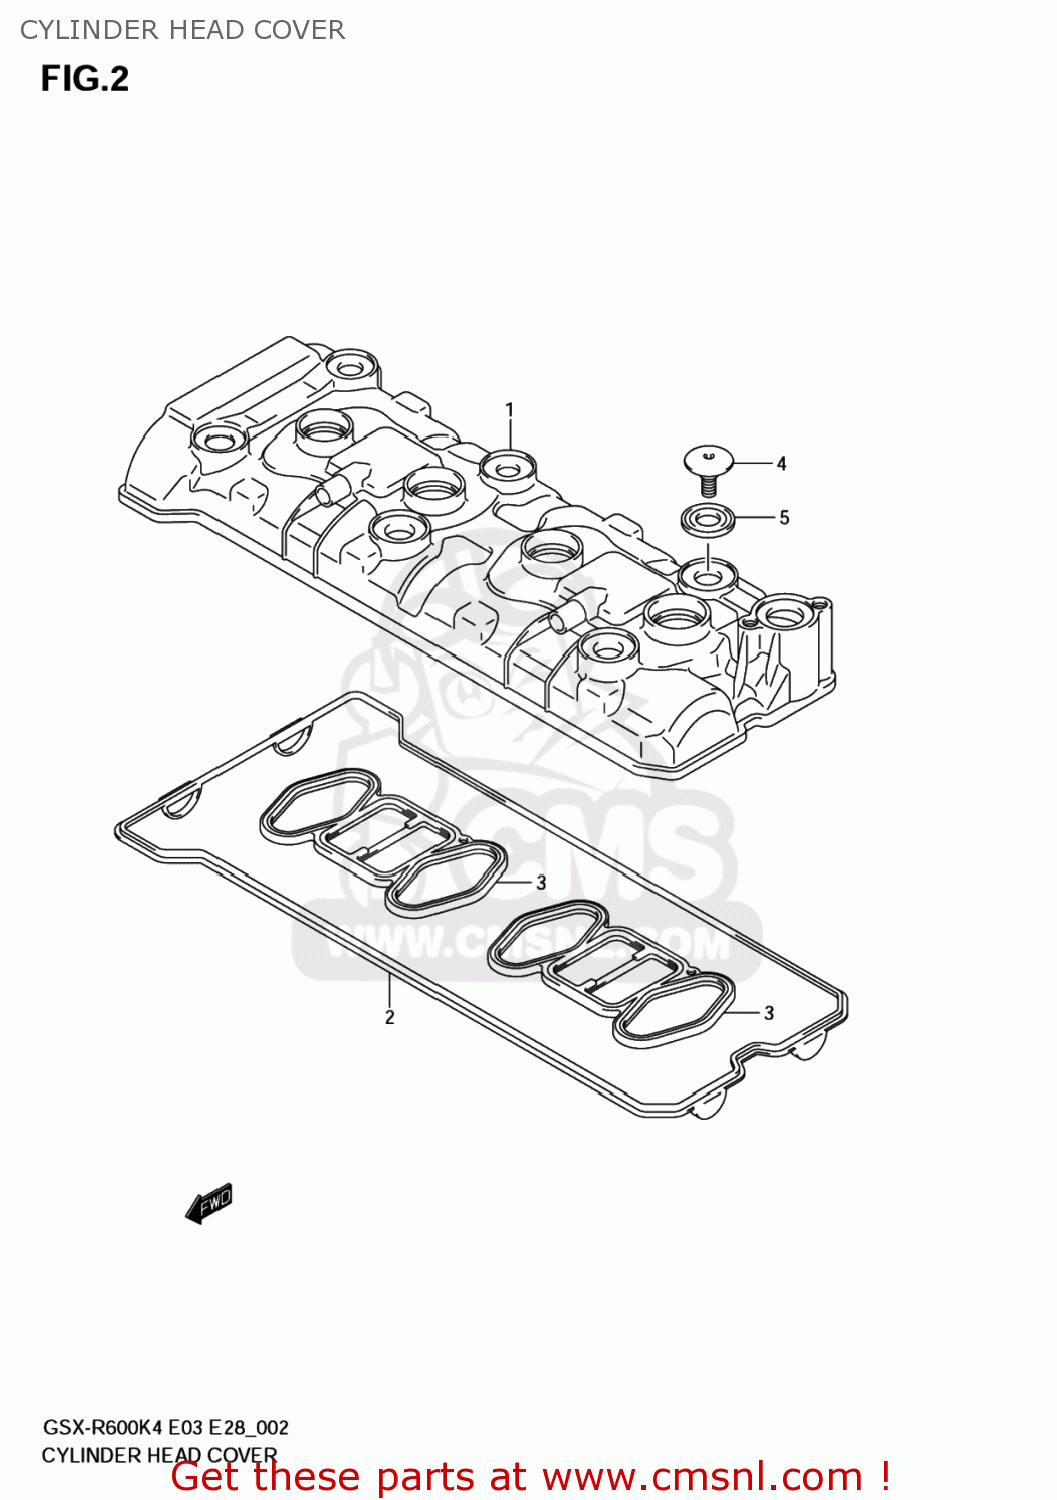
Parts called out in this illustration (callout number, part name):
1	COVER,CYLINDER HEAD
2	GASKET,CYL HEAD COVER NO.1 (NAS)
3	GASKET,CYL HEAD COVER NO.2 (NAS)
4	BOLT(7X17.5)
5	WASHER(10.6X25.5X2.3)
